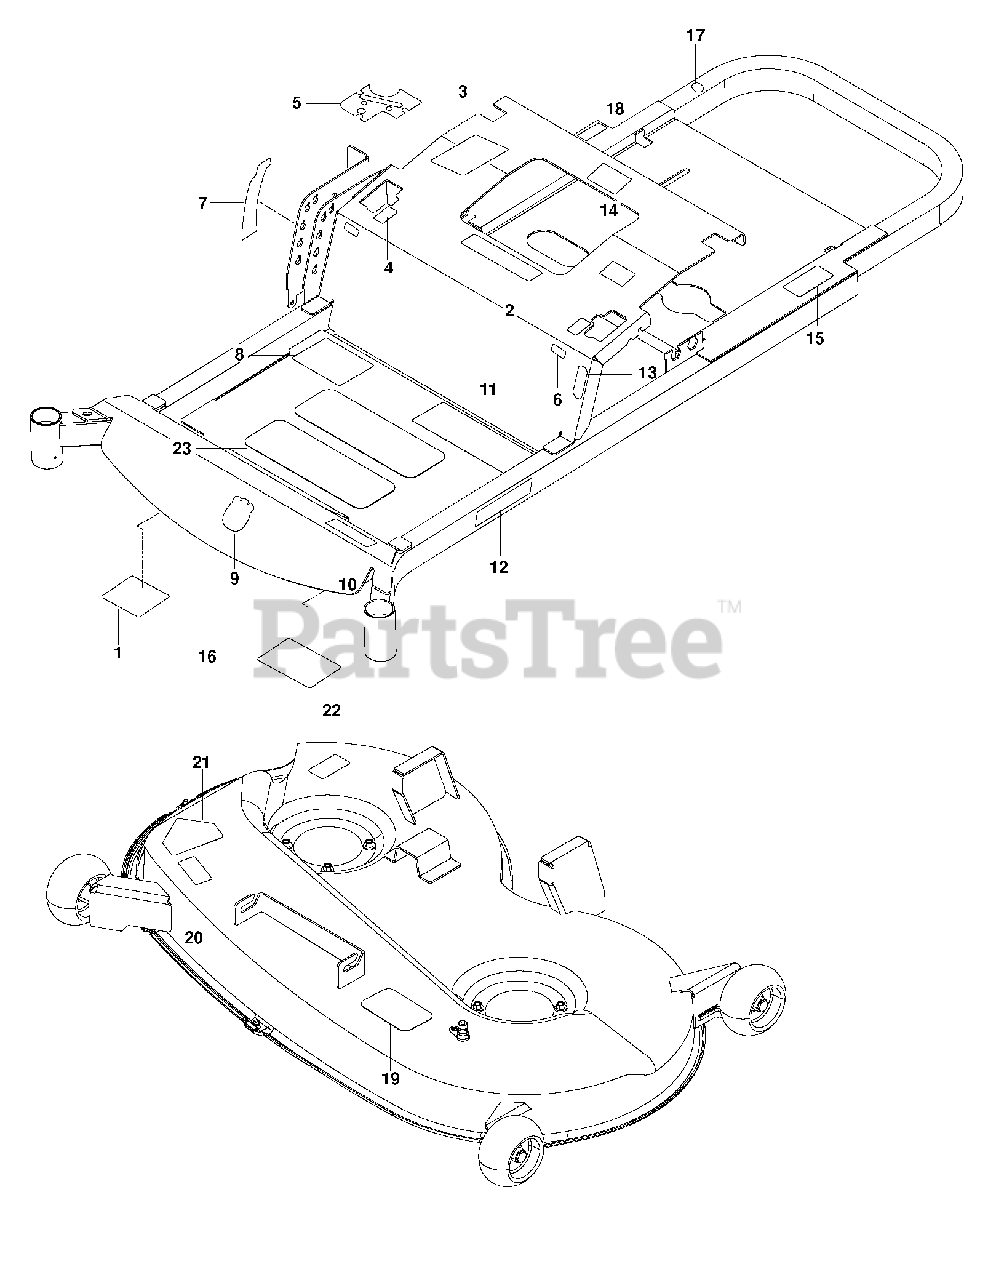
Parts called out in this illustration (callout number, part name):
2	EURO DECAL-BATTERY WARNIN6
3	DECAL, CUSTOMER RESPNSIBILITY
4	DECAL, MOTION CONTROL
5	DECAL.CNTRLPANEL.C/START.RZ
6	DECAL, F.S.T.
7	DECAL, DECK HEIGHT, HUSQ
8	DECAL ZTR STARTING
9	DECAL.AUGER.HUSQ.CROWN.SNOW
10	DECAL, RZ4623
11	DECAL.ZTR.WARNING.SMARTIGNITIN
12	RP.DECAL.BADGE.170MM.TEXTLOGO
13	DECAL, PARK BRAKE
14	DECAL, EXITING MOWER
15	DECAL, DO NOT TOW
16	DECAL, SERVICE
17	DECAL.E85.WARNING.2012
18	DECAL.FENDER
19	DECAL, BELT ROUTING
20	DECAL, EURO SEVERING
21	DECAL, CPSC
22	DECAL.DECK.6MIL./DEF.SHLD.WARN
23	ANTI-SKID PAD
